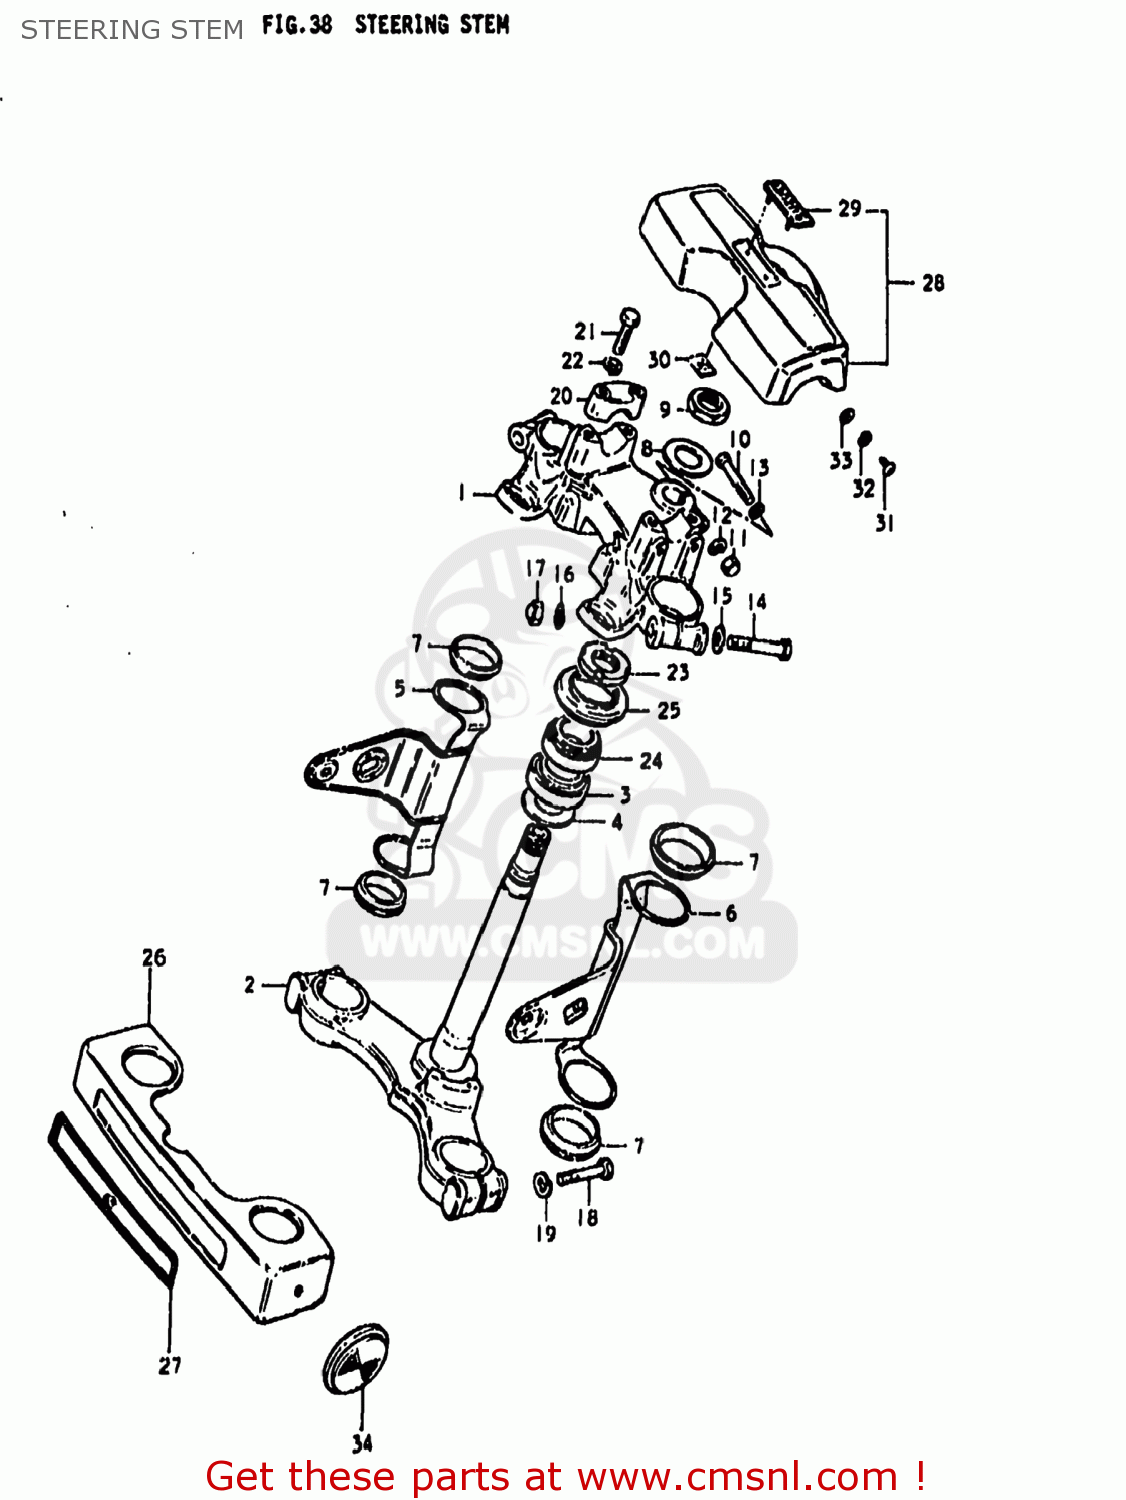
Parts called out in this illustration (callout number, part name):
1	HEAD,STEERING STEM
2	STEM,STEERING
3	BEARING
4	WASHER,THRUST
5	BRACKET,HEADLAMP,RIGHT
6	BRACKET,HEADLAMP,RIGHT
7	CUSHION,HEADLAMP BRACKET
8	WASHER
9	NUT,FR FORK UPR BRACKET
10	BOLT 8X50
11	NUT
12	LOCK WASHER
13	WASHER
14	BOLT 10X55
15	WASHER
16	LOCK WASHER
17	NUT, LOWER LH
18	BOLT
19	LOCK WASHER
20	HOLDER,HANDLE(BLACK)
21	BOLT
22	LOCK WASHER
23	NUT,STEERING STEM(25X44X10)
24	TAPER,ROLLER BEARING
25	DUST SEAL,STEERING,UPPER
26	COVER,FRONT FORK
27	EMBLEM
28	PAD,HANDLEBAR
29	EMBLEM,HANDLE COVER PAD
30	NUT
31	SCREW
32	LOCK WASHER
33	WASHER
34	REFLEX REFLECTOR,RR
